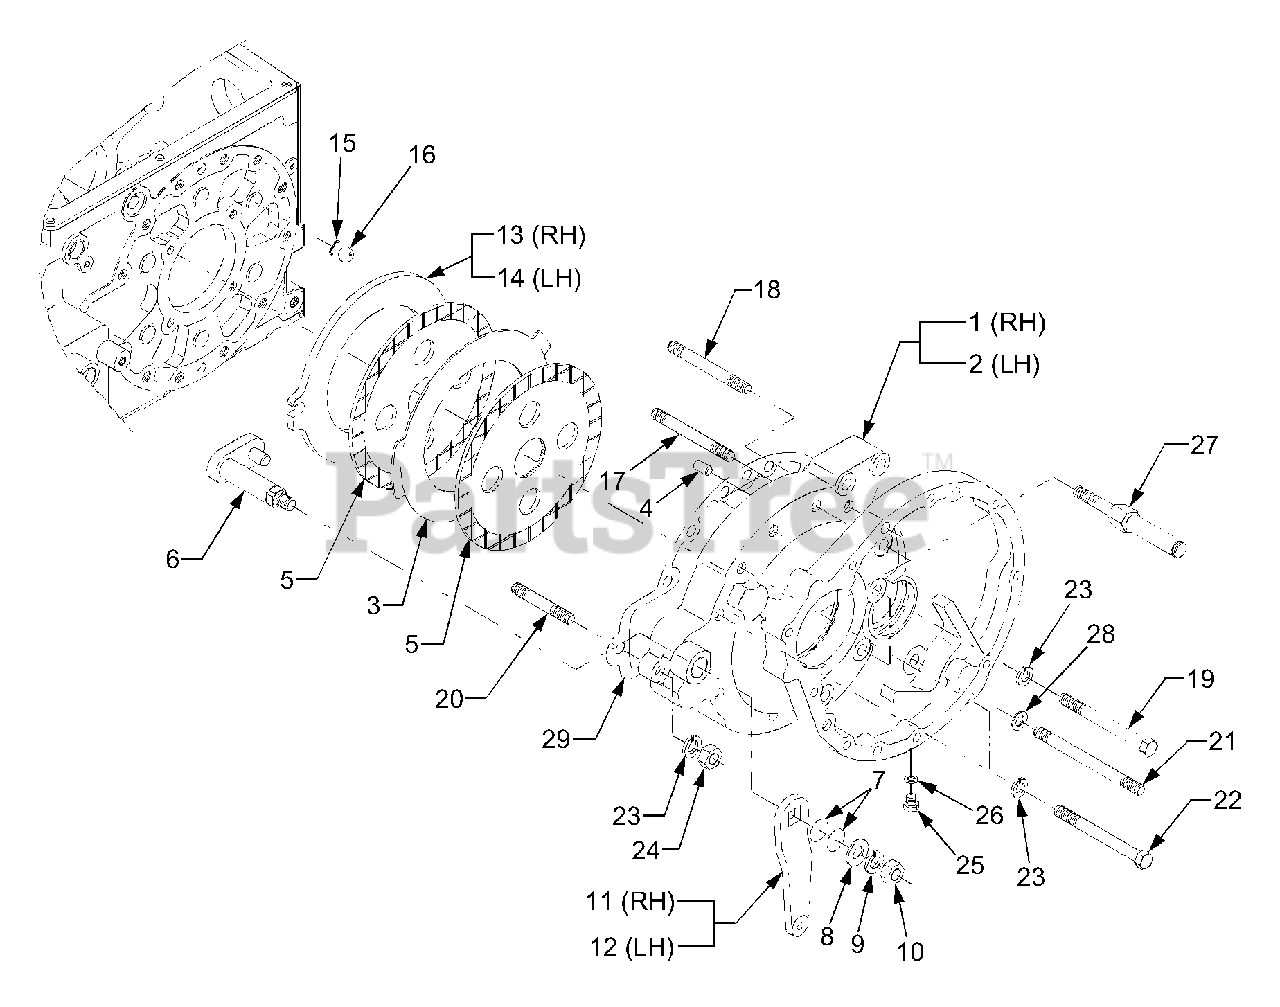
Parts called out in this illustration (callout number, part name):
1	Case, Brake(LH)
2	Case, Brake(RH)
8	Washer, Plain
9	Washer, Spring
11	Lever, Brake Cam(RH)
12	Lever, Brake Cam(LH)
13	Plate, Cam(RH)
14	Plate, Cam(LH)
23	Washer, Spring
27	Shaft, Lever (Range)
